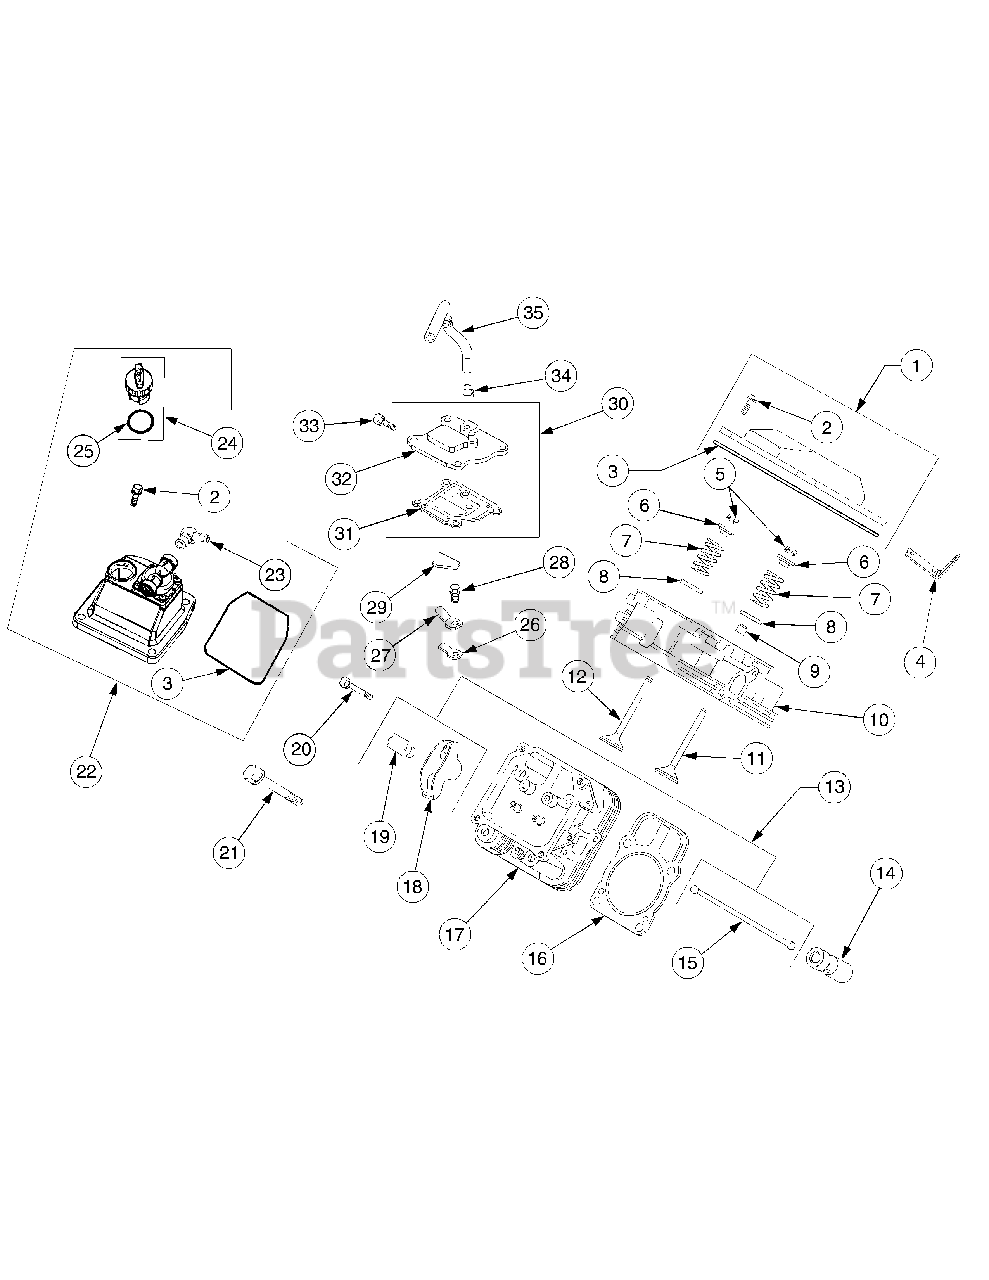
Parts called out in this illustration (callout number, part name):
1	Kit, Valve Cover (Includes 2-3)
2	Screw, Hex Flng, M6 x1.0 x 30
3	O-Ring, Valve Cover
4	Strap, Lifting
5	Kit, Retainer
6	Cap, Valve Spring
7	Spring, Valve
8	Retainer, Spring
9	Seal, Valve Stem
10	Head Assembly, #1 Cylinder
11	Valve, Intake Std
11	Valve, Intake, .25mm
12	Valve, Exhaust Std
12	Valve, Exhaust, .25mm
13	Kit, Valve Train (Incl. 15,18,19)
14	Lifter, Valve
16	Kit, Cyl. Hd. Gasket (Includes 21)
17	Head Assembly, #2 Cylinder
19	Pivot, Rocker Arm
20	Screw, Hex Flng, M6 x 1.0 x 34
21	Screw, Hex Flng, M10 x 1.5 x 90
22	Kit, Fuel Pump Valve Cover
23	Fitting, 90°
24	Cap Assembly, Oil Fill (Incl. 26)
25	O-Ring
26	Reed, Breather
27	Retainer, Breather Reed
28	Screw, Hex Flng, M5 x 0.8 x 10
29	Filter, Breather
30	Kit, Breather (Includes 32-34)
31	Gasket, Breather
32	Cover, Breather
33	Screw, Hex Flng M6 x 1.0 x 20
34	Clamp, Breather
35	Hose, Breather
